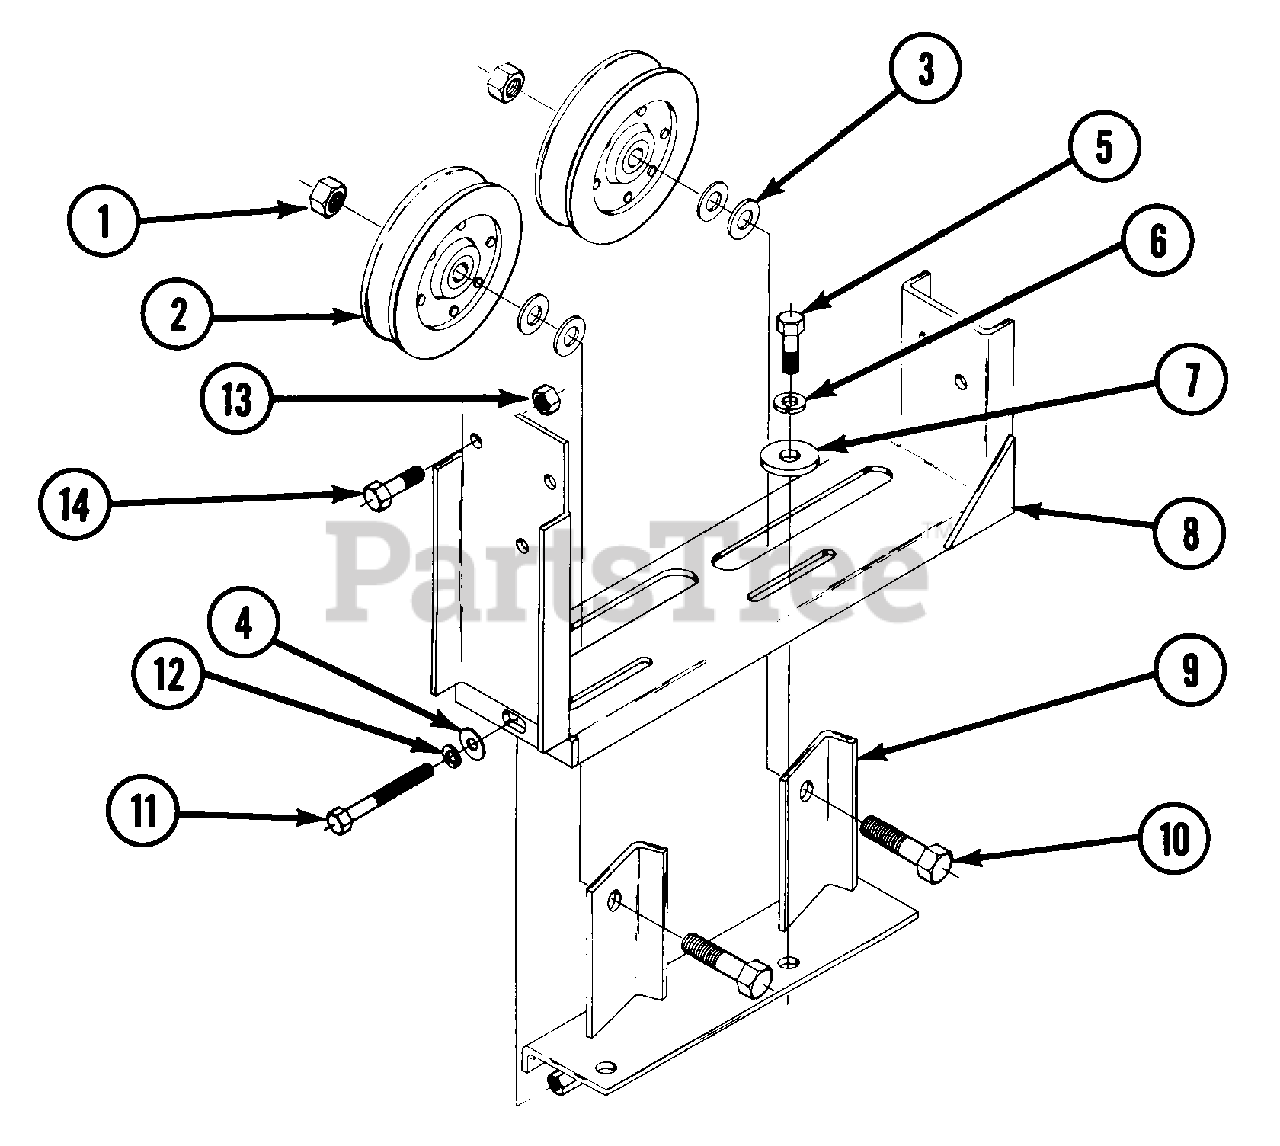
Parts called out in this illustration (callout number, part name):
1	LOCKNUT, HEX, 1/2-13, W/NYLOC
2	IDLER PULLEYS V, 4-3/8 OD, 1/2 BORE
3	WASHER 1/2 STD, FLAT
4	WASHER, 5/16 STD, FLAT
5	CAPSCREW, HEX, 3/8-16 X 1, GRADE 5
6	LOCKWASHER, 3/8 HEAVY, SPLIT SPRING
7	WASHER, .406 ID X 1.25 OD X .168 THK
8	MULE DRIVE IDLER MOUNT WELDMENT
9	SLIDE PLATE WELDMENT
10	CAPSCREW, HEX, 1/2-13 X 2, GRADE 5
11	CAPSCREW, HEX, 5/16-18 X 2-1/2, GRADE 5
12	LOCKWASHER, 5/16 HEAVY, SPLIT SPRING
13	LOCKNUT, HEX, 3/8-16, W/NYLOC
14	CAPSCREW, HEX, 3/8-16 X 1, GRADE 5
